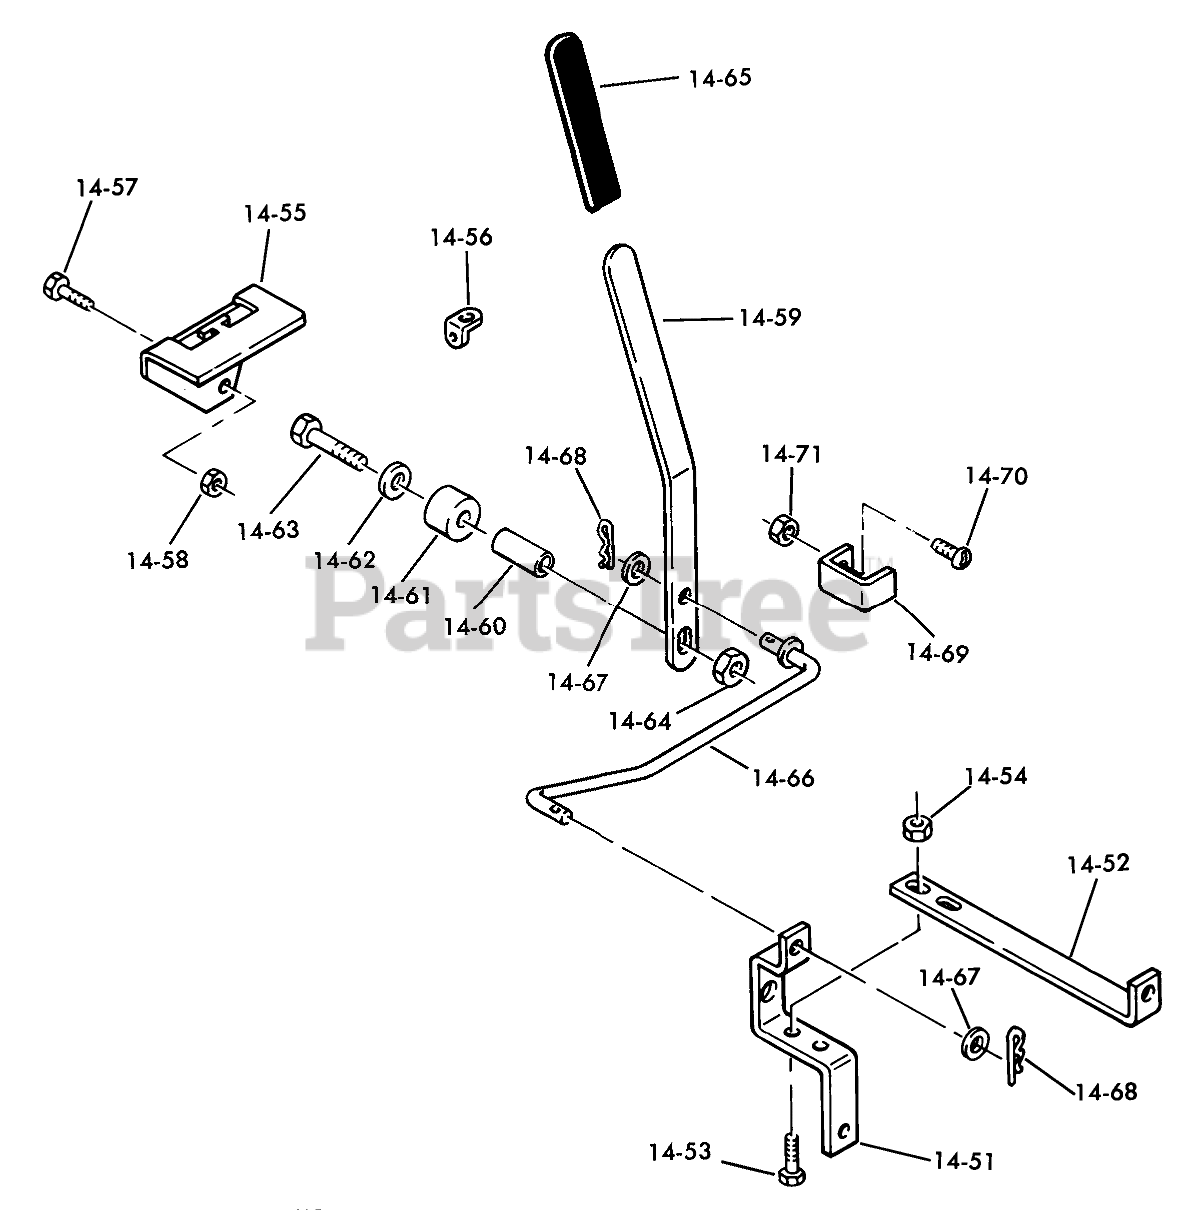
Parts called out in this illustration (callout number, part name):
14-51	Bar-Clutch Bell Crank
14-52	Bar-Locating
14-53	BOLT
14-54	Nut
14-55	Bracket-Clutch
14-56	CLIP - SPRING
14-57	BOLT
14-58	Nut
14-59	Clutch Lever Handle
14-60	SPACER HEIGHT ADJ
14-61	RUBBER BUMPER
14-62	Washer
14-63	BOLT
14-64	Nut
14-66	Mower Clutch Rod
14-67	WASHER-NYLON
14-69	Bracket
14-70	SCREW
14-71	Nut
